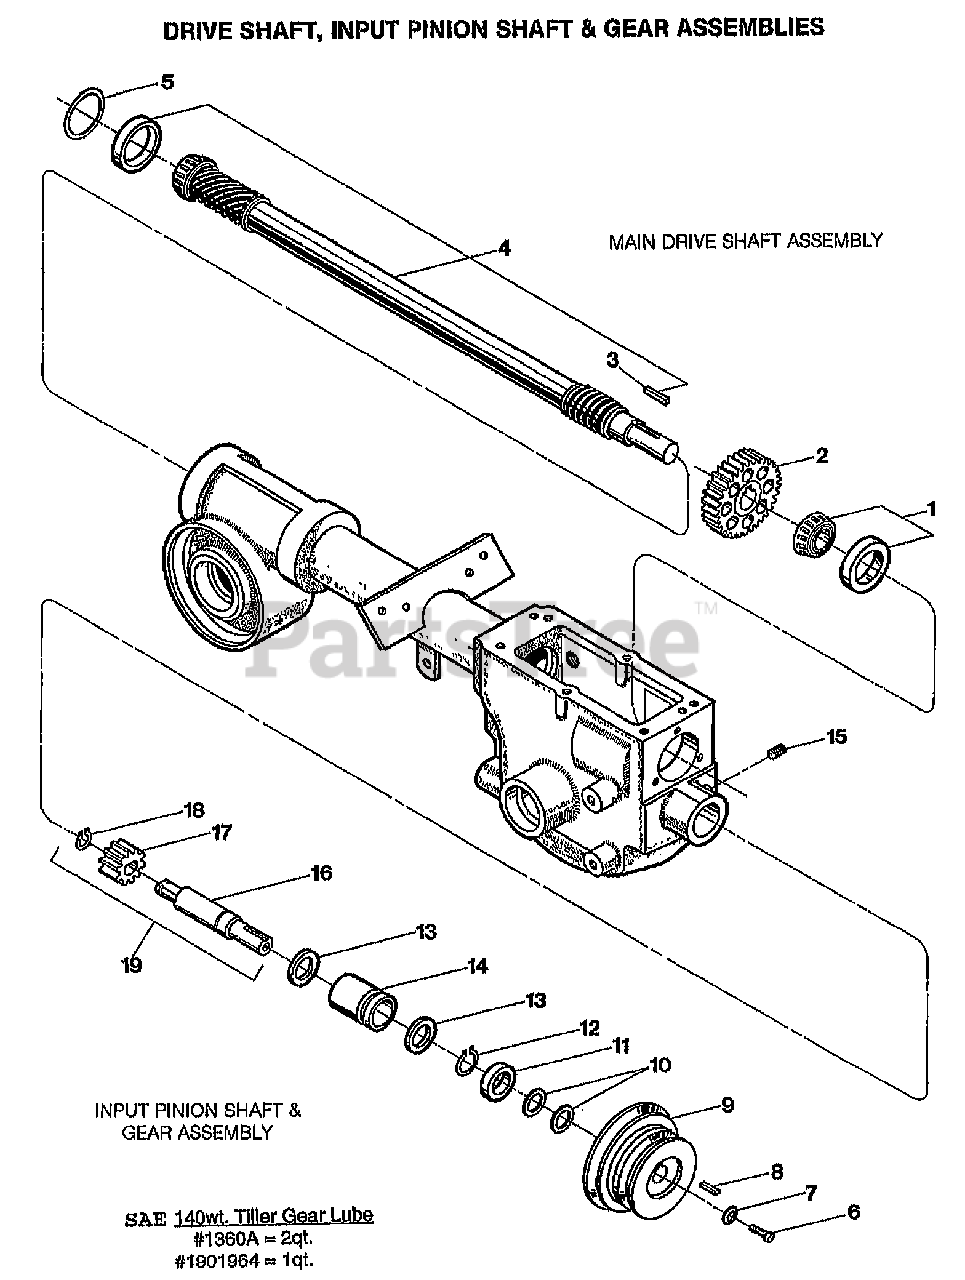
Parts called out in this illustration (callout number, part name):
1	KIT-BRG CONE&RACE-DRIVESHAFT (FRT OF DRV SHFT)
2	GEAR-SPUR 30 TEETH
3	KEY-.188 SQX1.0
4	KIT-DRIVESHAFT
5	SHIM-1.75X1.5X.01
5	SHIM-1.75X1.5X.03
5	SHIM-1.75X1.5X.005
6	SCR-HH 5/16-24X.75 G5 ZP
7	WASHER-.827X.331X.098 (CONCAVE SDE FACES PLLY)
8	KEY-.188 SQX1.0
9	PULLEY-TRANS MACH
10	WASHER # .875 X .65 X .06
11	SEAL-PINION SHAFT PT/85030/00
12	RING-RETAIN EXT .707 ID
13	WASHER-1.022X.752X .059
14	BUSHING-1.24X.75X1.8 GRVD
15	SCR-SS 5/16-18X.375
16	SHAFT-PINION(P-V)
17	GEAR-PINION P/M
18	RING-BOWED EXT .461 ID
19	PINION W/GEAR&SNAP RING
